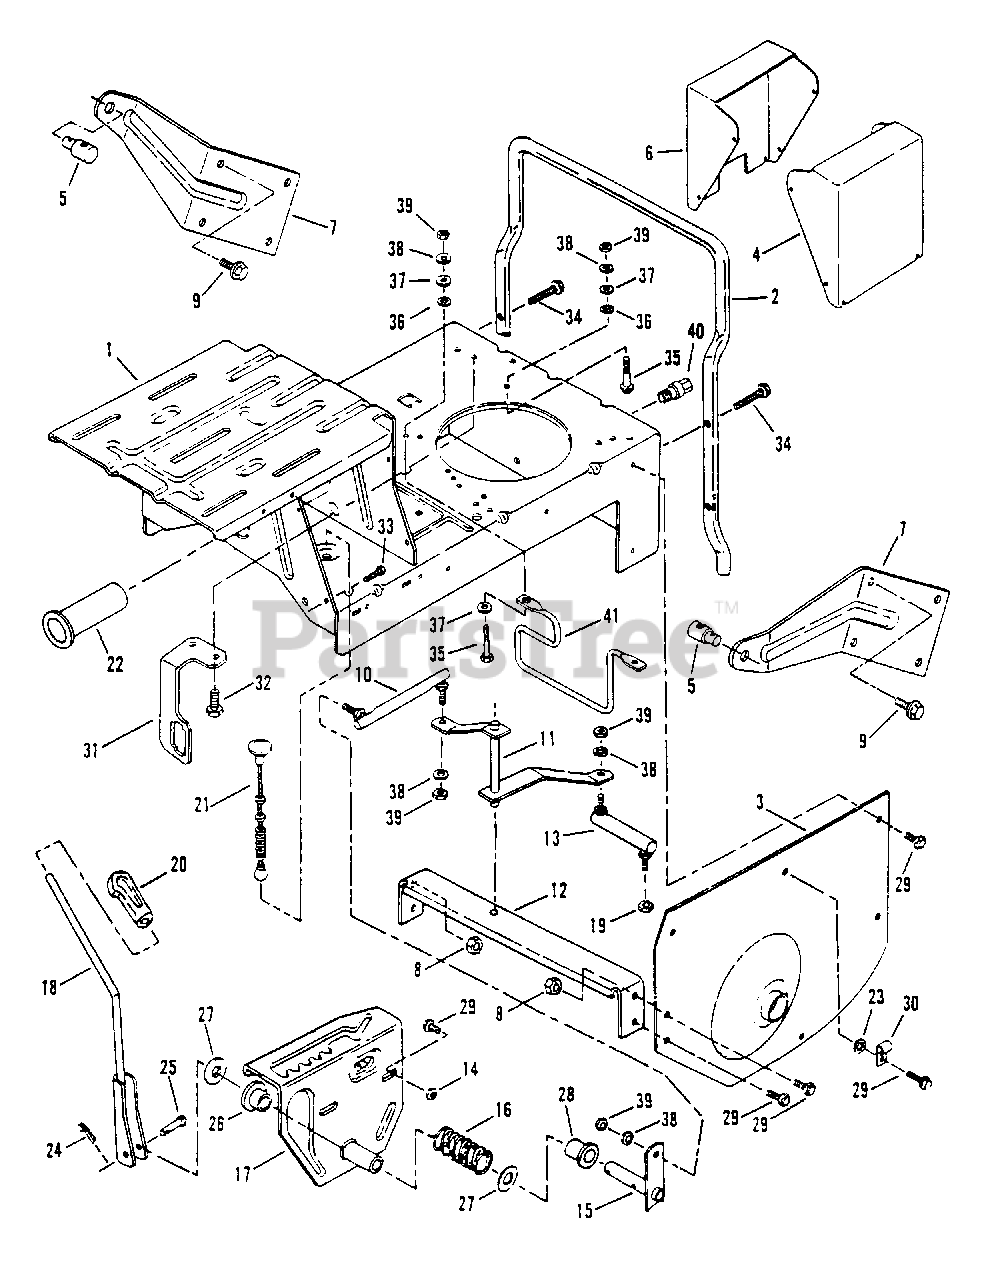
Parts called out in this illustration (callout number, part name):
1	CASE, Main (Standard)
2	BUMPER, Rear
3	FENDER, Left Hand
4	COVER, Battery
5	SWIVEL
6	COVER, Switch
7	WING, Rear
8	NUT, 5/16-18 Hex Flange Lock
9	SCREW, 5/16-18 x 3/4" Self-Tapping
10	LINK, Shift (Long)
11	ARM, Shift
12	BRACE, Cross
13	LINK, Shift (Short)
14	NUT, 5/16-18 Hex
15	ARM, Shift Handle
16	SPRING, Shift Handle
17	DETENT, Shift
18	HANDLE, Shift
19	NUT, Flange Lock 5/16-24
20	KNOB, Shift Handle
21	CABLE, Deck Support
22	BUSHING, Pilot
23	WASHER, 5/16 Internal Tooth Lock
24	PIN, 3/32 x 3/4" Cotter Hair
25	PIN, 1/4 x 1-3/4" Tapered Clevis
26	BUSHING, Nylon
27	WASHER, Thrust
28	BUSHING, Nylon
29	SCREW, 5/16-18 x 5/8" Self-Tapping
30	CLIP, Wire
31	BRACKET, Switch
32	SCREW, Self Tapping, 10-32 x 1/4
33	FASTENER, 1/4 x 3/4 Ratchet
34	SCREW, 5/16-18 x 1-1/2" Self-Tapping
35	SCREW, 5/16-24 x 1-3/4" Hex Head Cap
36	RETAINER, 5/16 Bolt
37	WASHER, 5/16" Flat
38	WASHER, 5/16" Split Lock
39	NUT, 5/16-24 Hex
40	DRAIN, Oil (Short)
41	GUIDE, Belt
